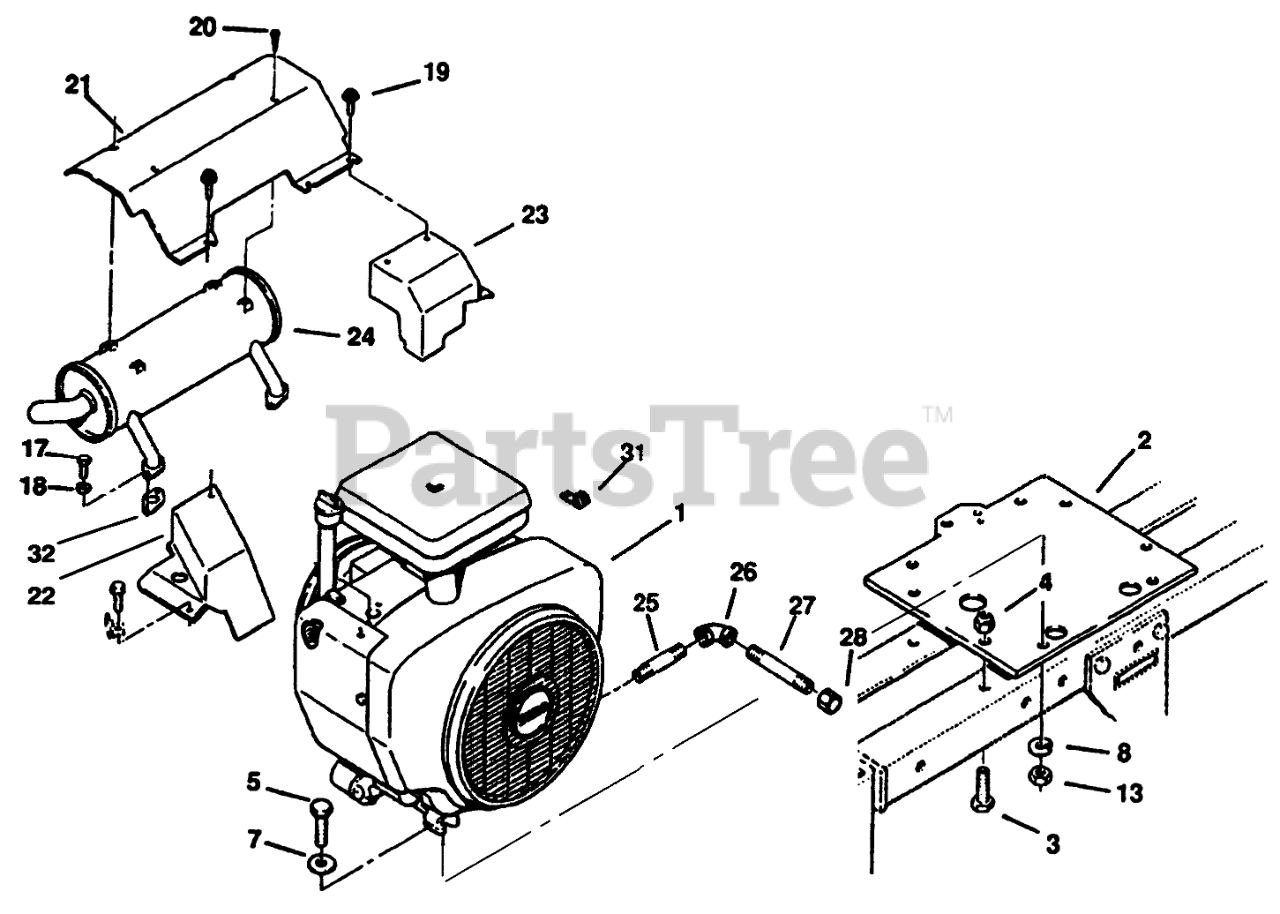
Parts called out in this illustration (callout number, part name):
1	Engine-Onan
2	PLATE-ENGINE B
3	SCREW-HH
4	NUT-LOCK, NI
5	SCREW-HH
7	WASHER-FLAT
8	WASHER-LOCK
13	NUT-HEX
17	SCREW-HH
18	WASHER-LOCK
19	SCREW
20	SCREW
21	BAFL DEFLCTORB
22	LH Exhaust Cover
23	RH Exhaust Cover
24	MUFFLER-EXHAUST
25	Pipe
26	ELBOW 3/8 90 DEG
27	PIPE-NIPPLE 3/8 X 4"
28	CAP-PIPE
30	Exhaust Gasket
31	J-CLIP
32	GASKET
